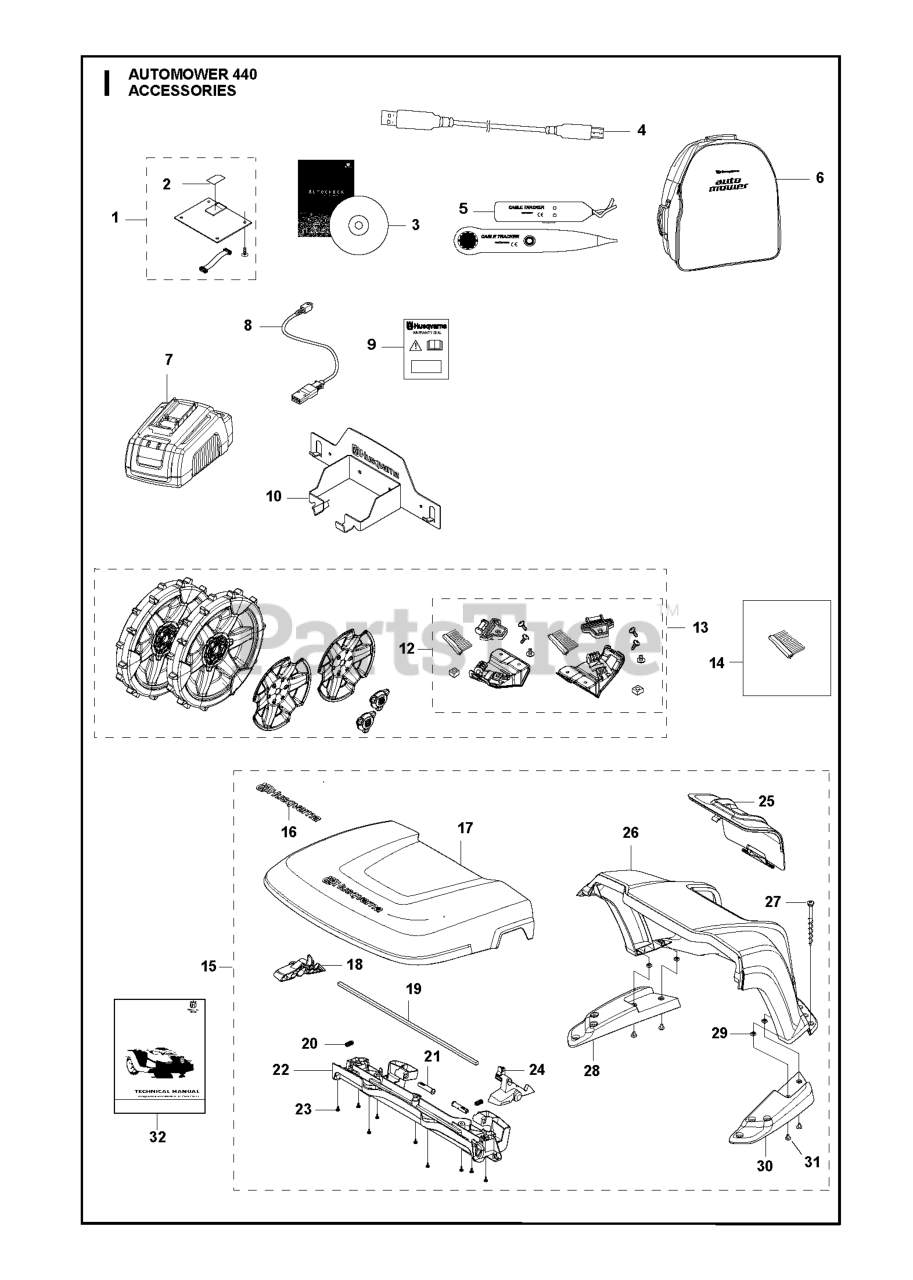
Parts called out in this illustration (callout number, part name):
1	CONNECT MODULE 315 / 430X
3	DVD AUTOCHECK EXP SERVICE
4	CABLE WHITE ALT GREY
5	TEST EQUIPMENT
6	BAG
7	CHARGER BATTERY TEST
8	CABLE ASSY QUICK CHARGER
9	LABEL WARRANTY SEAL DEALER
10	MISC. BLISTER WALL HANGER
12	BRUSH KIT 430/450
13	REAR WHEEL KIT W/ BRUSHES
14	WHEEL BRUSH REFILL KIT
15	430/450 HOUSE KIT
16	DECAL.HUSQVARNA.210MM
17	KIT LID - AUTOMOWER HOUSE
18	HANDLE RELEASE LEFT
19	ROD
20	SPRING SPRING CAP
21	HINGE PIN
22	BEAM
23	SCREW 14MM
24	HANDLE RELEASE RIGHT
25	HATCH
26	COVER BASE P2 HOUSE
27	SCREW KIT CS
28	SUPPORT BASE LEFT
29	NUT
30	SUPPORT BASE RIGHT
31	SCREW IHPANM M6X25 4.6 ZP-BC
